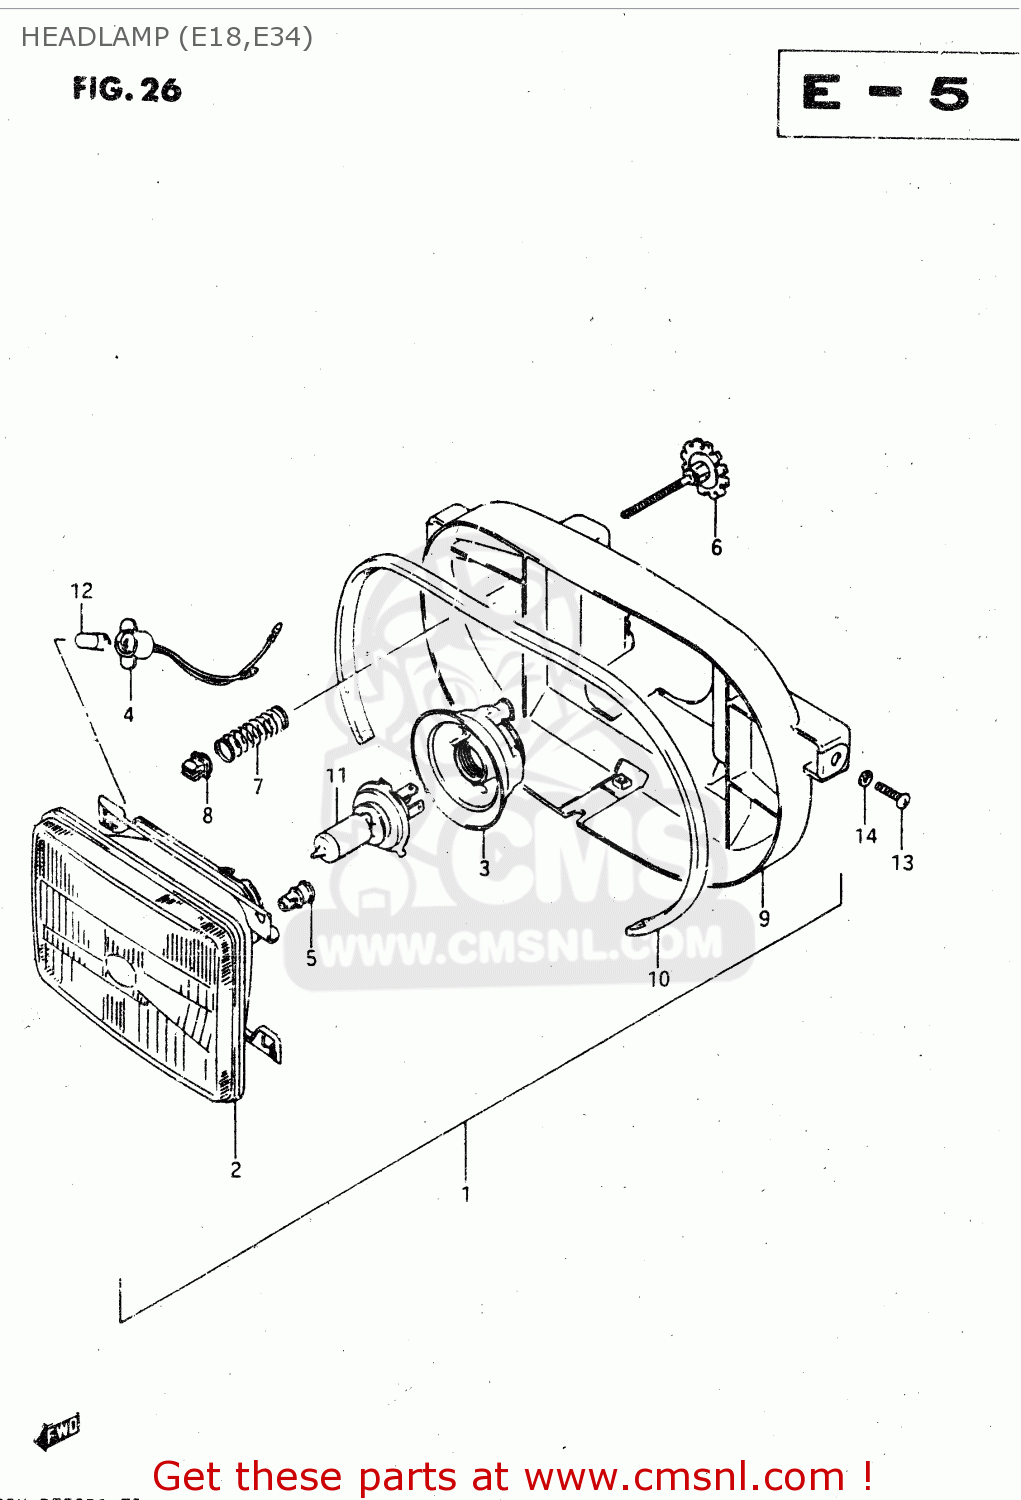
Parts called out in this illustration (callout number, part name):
1	HEADLAMP ASSY
2	UNIT
3	COVER,HEADLAMP SOCKET
4	SOCKET
5	SCREW,SPHERICAL
6	SCREW,ADJUSTER
7	SPRING
8	NUT
9	HOUSING
10	GASKET (NAS)
11	BULB(12V60/55W,H4)
12	BULB(12V4W)
13	SCREW
14	WASHER,LOCK
